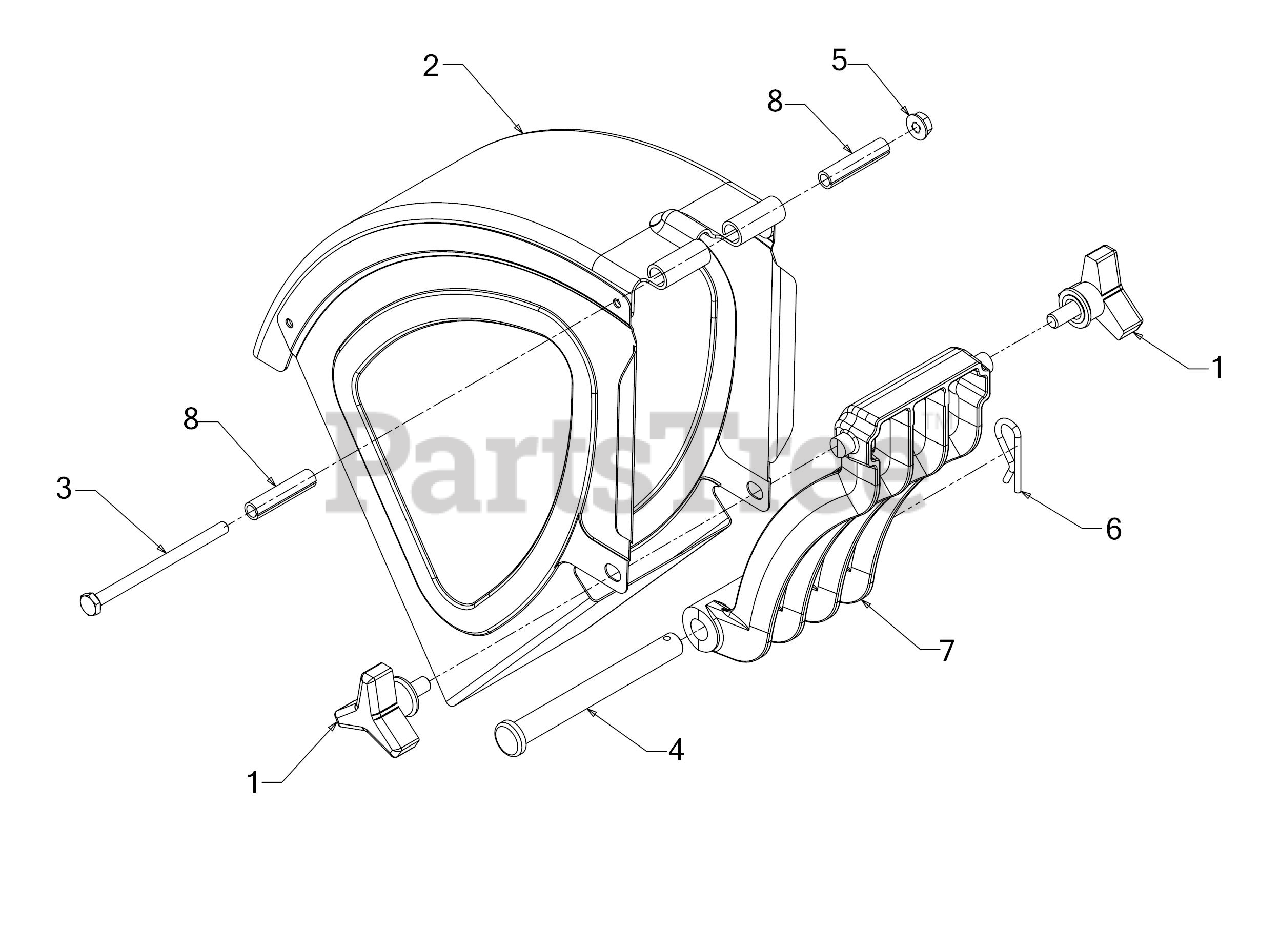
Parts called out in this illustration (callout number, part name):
1	KNOB ASSEMBLY
2	DISCHARGE CHUTE ASSEMBLY
3	SCREW 1/4-20 X3.75 GR5
4	CLEVIS PIN
5	LOCK NUT 1/4
6	COTTER PIN
7	SHREDDER SCREEN
8	SPACER-.260 x .3
